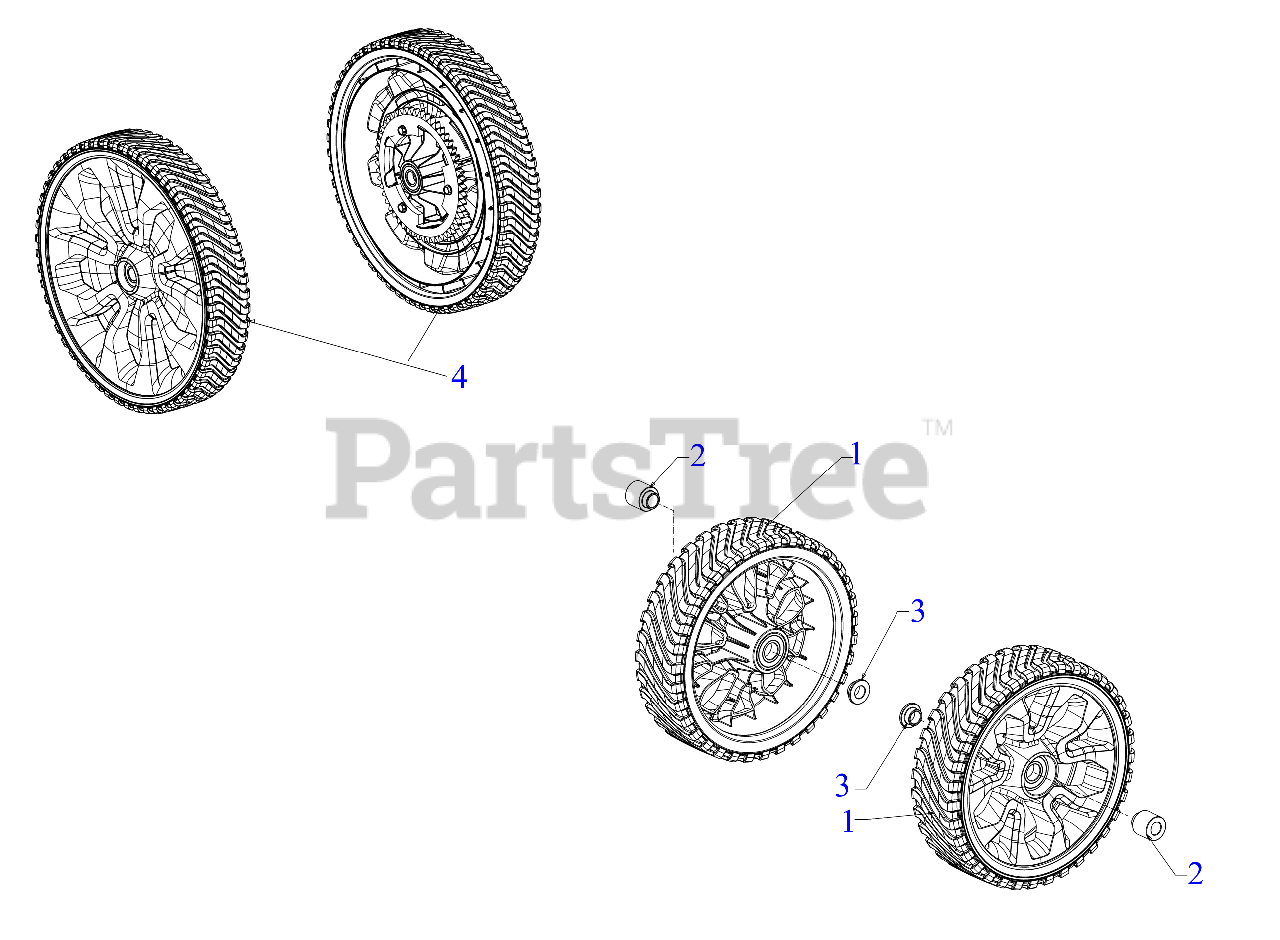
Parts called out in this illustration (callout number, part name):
1	WHEEL ASSEMBLY 7 x 2 GRAY BB
3	CASTER HUB
4	DRIVE WHEEL ASSEMBLY 11 x 2 GRAY
